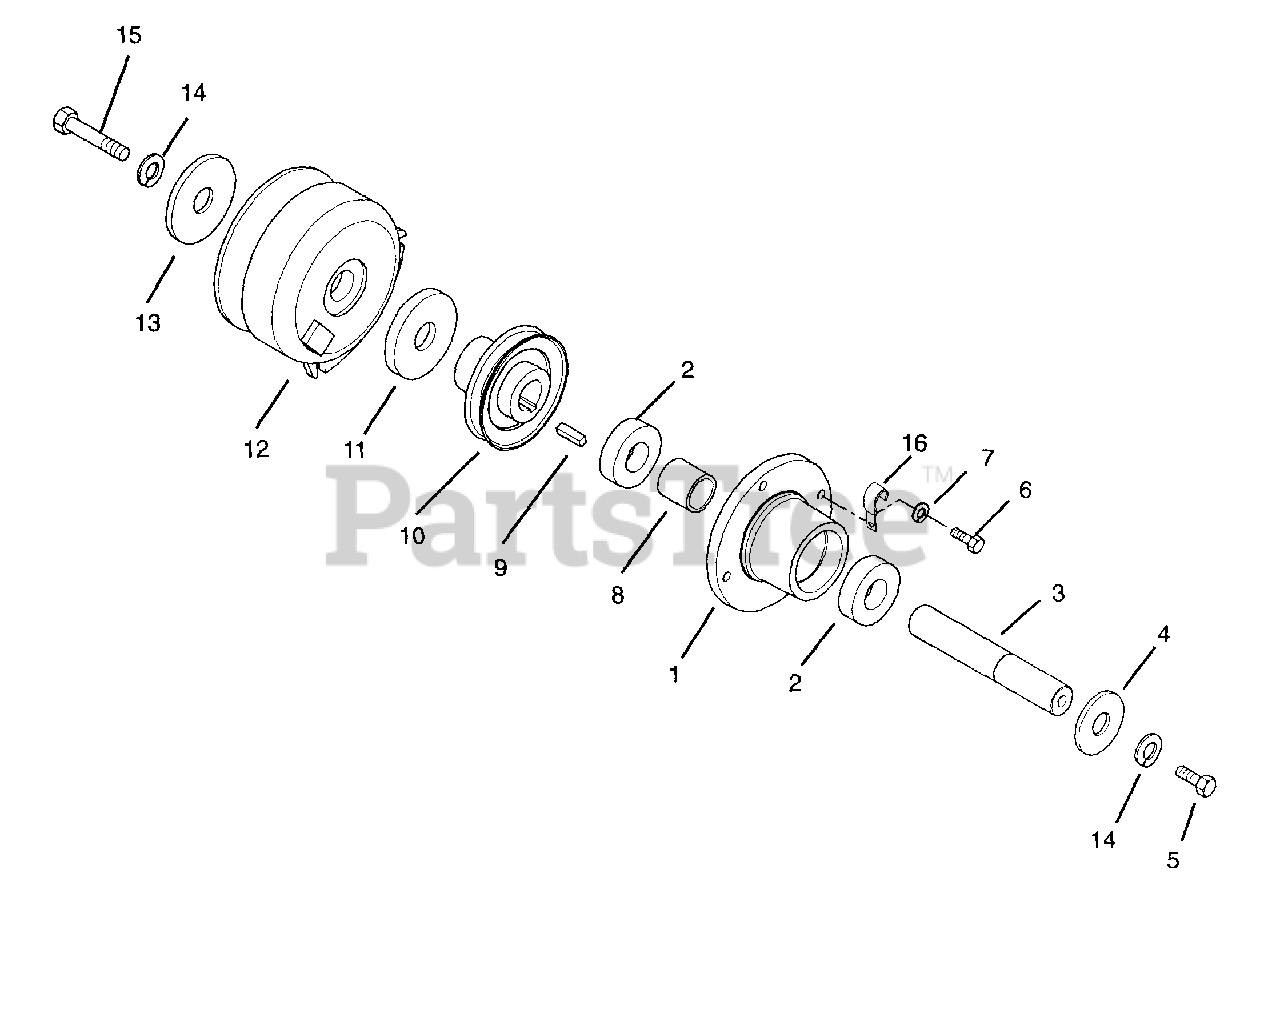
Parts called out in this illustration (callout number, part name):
1	HOUSING, TRANS SPNDL, BLACK
2	BRG-BALL .984X2.04X.59
3	SHAFT, JACK
3	SHAFT 1540/1648
4	WSHR-FL-STL.463X1.375X.25 YWZC
5	BLT-HEX .44-20X1.00 GR5 YWZC
6	@BLT-HEX .31-18X.75 GR5 YWZC
7	@WSHR-LK .31X.078 REG YWZC
8	SPACER 1.0X1.253X1.26
9	KEY-SQ .25X1.0X.25 SAE 8630
10	SHEAVE, JACKSHAFT
11	SPACER 1.004X1.500X.740
11	CLUTCH SPACER - 48"
12	ELECTRIC CLUTCH/BRAKE(1.8AMP)
12	CLUTCH, ELECTRIC - WARNER
12	ELECTRIC CLUTCH/BRAKE (3.4AMP)
13	WSHR-FL-STL .469X2.00X.25 YWZC
14	WSHR-LK .438X.133 HVY YWZC
15	BLT-HEX .44-20X2.50 GR5 YWZC
15	BLT-HEX .44-20X1.5 YWZC
16	J-CLAMP
